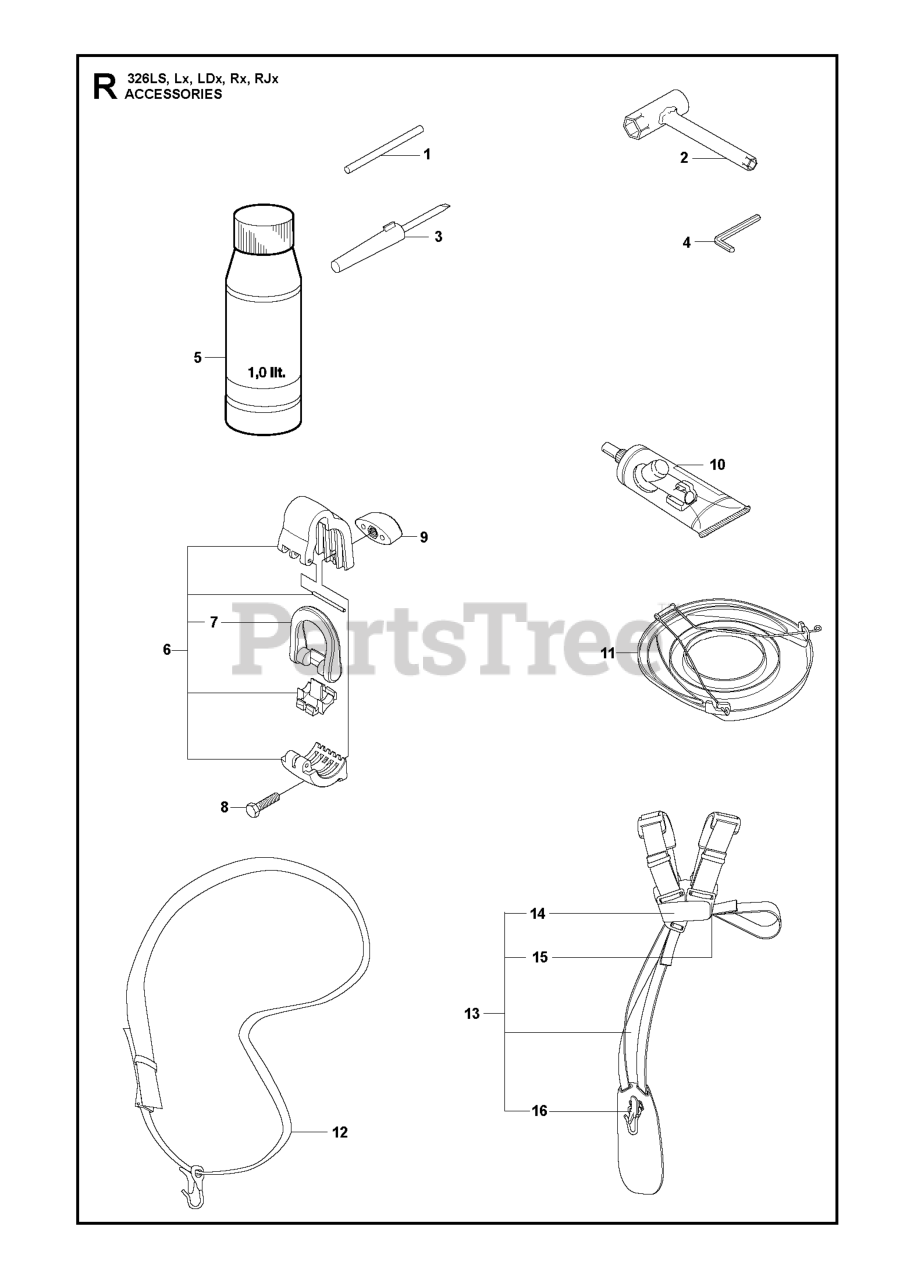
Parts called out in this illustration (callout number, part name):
1	LOCKING PIN
2	COMBI WRENCH
3	SCREWDRIVER
4	L-KEY WRENCH
5	Air Filter Oil 1l.
6	HANGING BRACKET
8	SCREW M6S 5X20
10	BEVEL GEAR GREASE
11	BLADE GUARD TRANSPORT
12	Harness-w/o warning
12	Harness - Diagonal with sign
13	HARNESS DUO
13	Harness w/warning
15	RIGHT FRONT HARNESS PC
16	HOOK, CPL.
